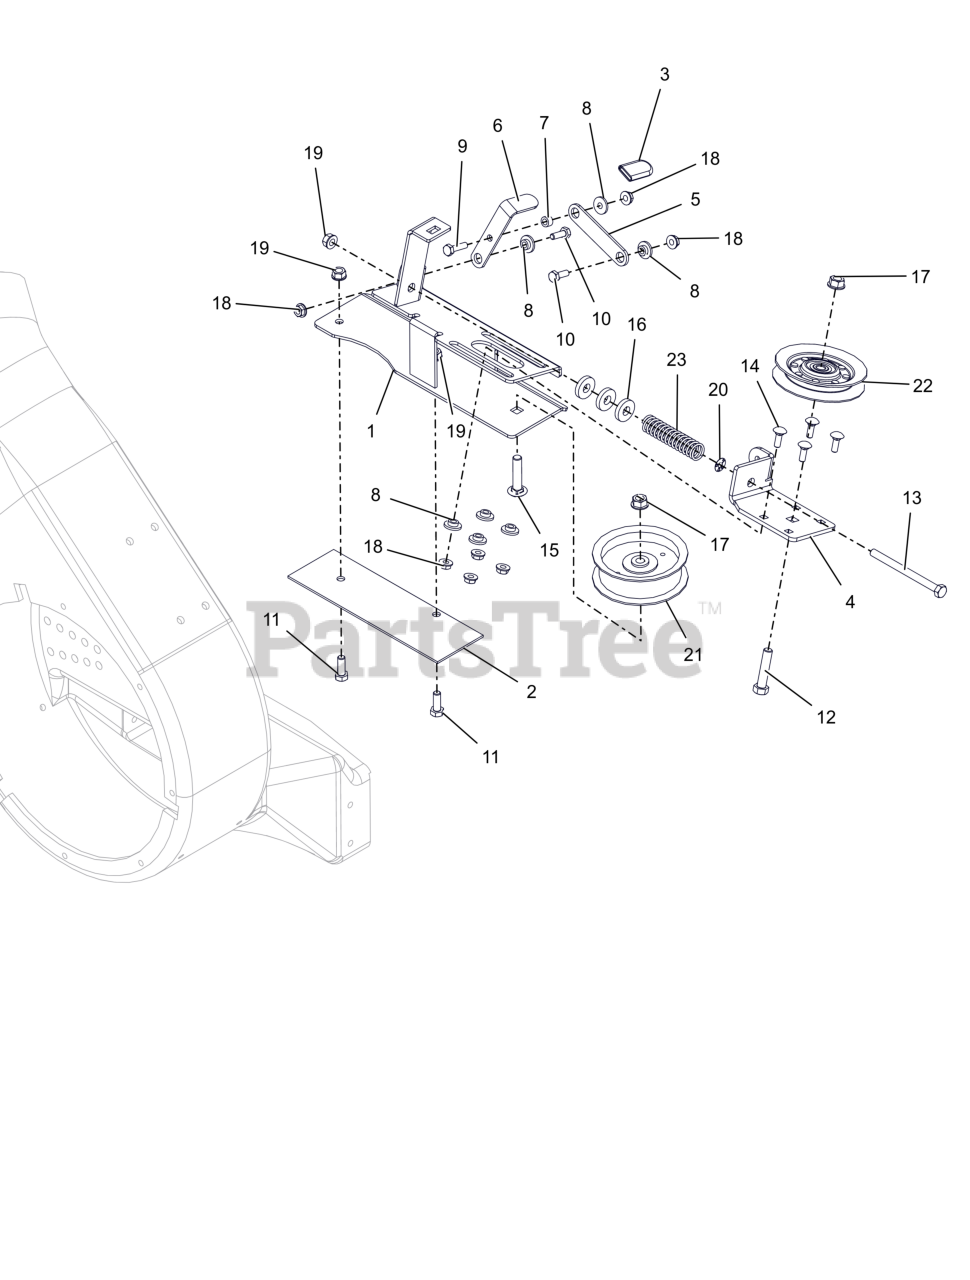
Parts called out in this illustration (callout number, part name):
1	WELDMENT, IDLER MOUNT -2015
2	PLATE,BACK
3	GRIP, SEAT LEVER, GREY
4	BRACKET, ADJ. PULLEY IDLER
5	LINK, TENSIONER
6	HANDLE, TENSIONER
7	BUSHING, .26 ID X .44 OD X .26
8	BSHG-FLG .265X.437X.250X.750
9	BLT,HEX .25-20X1.00 G5 ZCC
10	BLT, HEX .25-20X.75 G5 ZCC
11	BLT, HEX .31-18X.875 G5 ZCC
12	BLT, HEX .38-16X1.75 G5 ZCC
13	BLT, HEX .31-18X4.00 G5 ZCC
14	BLT, RHSN .25-20X.750 G5 ZCC
15	BLT, RHSSN .38-16X1.75 G5 ZCC
16	WSHR, FLT .406X1.00X.188 ZCC
17	NUT-LK-TOP-FLG .38-16 ZC120
18	NUT-LK-TOP-FLG .250-20 GF ZCC
19	NUT-LK-TOP-FLG .312-18 GF ZCC
20	NUT-PUSH .312
21	IDLER, FLG .38ID X 3.50
22	V-IDLER, 4.00X.38
23	SG-COMP .092X.77X3.13 WLD 36
